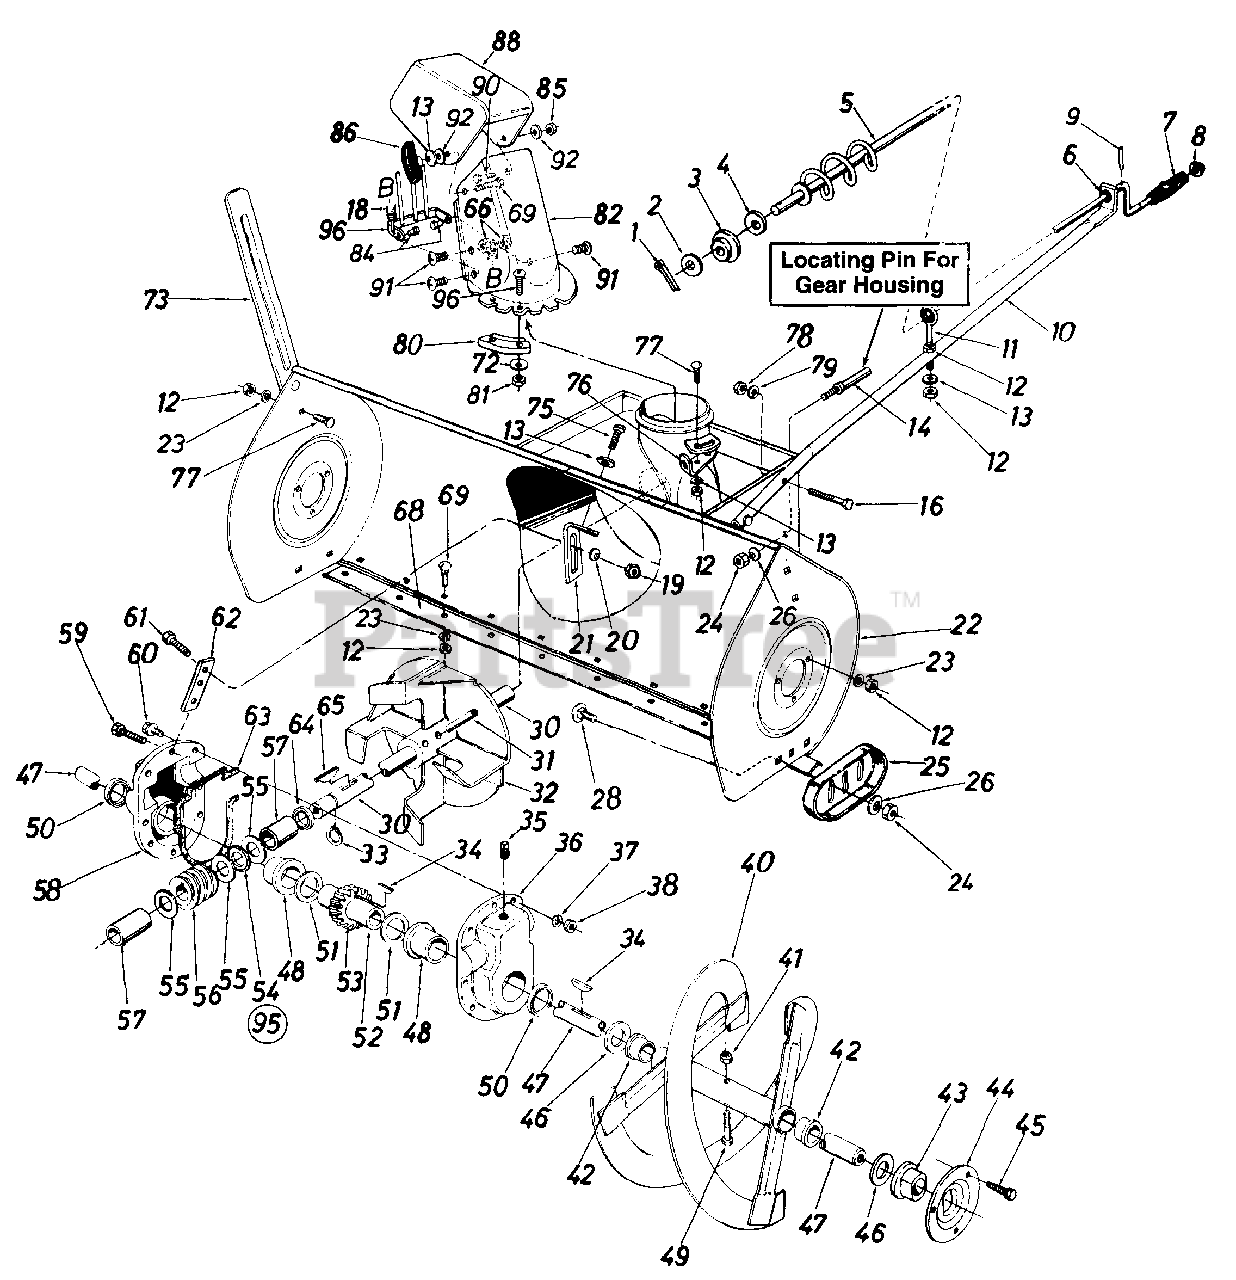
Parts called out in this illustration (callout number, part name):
1	Cotter Pin 3/32" x .75"
2	Fl-Wash. .385" I.D. x .62" O.D. x .06"
3	Plastic Bushing .380" I.D.
4	Fl-Wash. .385" I.D. x .62" O.D. x .06"
5	Chute Crank Ass'y.
6	Plastic Bushing .38" I.D.
7	Knob - Black
8	Cap Speed Nut 3/8" Rod
9	Spring Pin
10	Chute Crank Supporting Tube
11	Eyebolt Chute Crank Support
12	Hex Nut 5/16-18 Thd.
13	Bell-Wash. .345" I.D. x .88" O.D. x .06"
14	Belt Keeper Studs 3/8-16 x 2.75"
16	Hex Bolt 3/8-24 x 1.25" Lg.
18	Extension Spring
19	Hex Nut 1/4-28 Thd.
20	Bell-Wash. .25" I.D. x .88" O.D. x .062"
22	45" Snow Thrower Hsg. Ass'y.
23	L-Wash. 5/16" I.D.
24	Hex Jam Nut 3/8-16 Thd.
25	Reversible Slide Shoe
26	Bell-Wash. .4" I.D. x .88" O.D. x .06"
28	Carr. Bolt 3/8-16 x .62" Lg.
30	Blower Axle 14.75" Lg.
31	Spr. Spiral Pin - H.D.
34	#91 Woodruff Key 1/4" x 3/4" Dia.
35	Plastic Vented Plug 1/4-18 Pipe Thd.
36	Gear Hsg. Half - L.H.
37	Shakeproof Spr. Wash.
38	Hex Ins. L-Nut 5/16-18 Thd.
41	Hex Ins. L-Nut 5/16-18 Thd.
42	Flange Bearing
43	Flange Bearing w/Flats
44	Bearing Housing
45	Hex Sems Bolt 5/16-18 x .75" Lg.
48	Flange Bearing
49	Shear Bolt 5/16-18 x 1.75
50	Oil Seal 1.5" I.D. Garlock
51	Fl-Wash. 1.5" I.D. x .2" O.D. x .03"
52	Worm Gear Shaft
53	Worm Wheel - L.H. Double Thd.
54	Thrust Brg. .88" I.D. x 1.44" O.D. x .078"
55	Fl-Wash. .88" I.D. x 1.4" O.D. x .125"
56	Worm Gear - L.H. Double Thd.
57	Sleeve Brg. .875" I.D.
58	Gear Hsg. Half - R.H.
59	Hex Bolt 5/16-18 x 1.25" Lg.
60	Hex Bolt 5/16 x 1" Lg.
61	Hex Bolt 1/4-28 x .75" Lg.
62	Gear Hsg. Support Plate
63	Rubber Gasket
64	Oil Seal for .875" I.D. Garlock
65	#9 Hi-Pro Key 3/16" x 3/4" Dia. - H.T.
66	Hex L-Nut 1/4-20 Thd.
69	Carr-Bolt 5/16-18 x 1" Lg.
72	Fl-Wash. .281" I.D. x .5" O.D. x .063"
75	Hex AB-Tap Scr. 5/16 x .75" Lg.
77	Carr. Bolt 5/16-18 x .75" Lg.
78	Hex Nut 3/8-24 Thd.
79	L-Wash. 3/8" I.D.
80	Chute Flange Keeper
81	Hex L-Nut 1/4-20 Thd.
82	Lower Chute
84	Shld. Nut 1/4-20 Thd.
85	Hex L-Nut 5/16-18 Thd.
86	Hand Knob
88	Upper Chute
90	Truss Mach. Scr. 5/16-18 x .75" Lg.
91	Truss Mach. Scr. 1/4-20 x .5" Lg.
92	Fl-Wash. .344" I.D. x 1.125" O.D. x .125"
95	Gear Box Ass'y. Complete
96	Truss Mach. Scr. 1/4-20 x 3/4" Lg.
05139A-0637	BLADE-GUIDE (DRIFT - POWDER BLACK (0637)
05139A-0638	BLADE-GUIDE (DRIFT - MTD/TROY-BILT RED (0638)
05139A-0662	BLADE-GUIDE (DRIFT - OYSTER GRAY (0662)
05139A-0665	BLADE-GUIDE (DRIFT - YARDMAN GREEN (0665)
05139A-0674	BLADE-GUIDE (DRIFT - YARDMAN YELLOW (0674)
05139A-0716	BLADE-GUIDE (DRIFT - CUB YELLOW-99 (0716)
